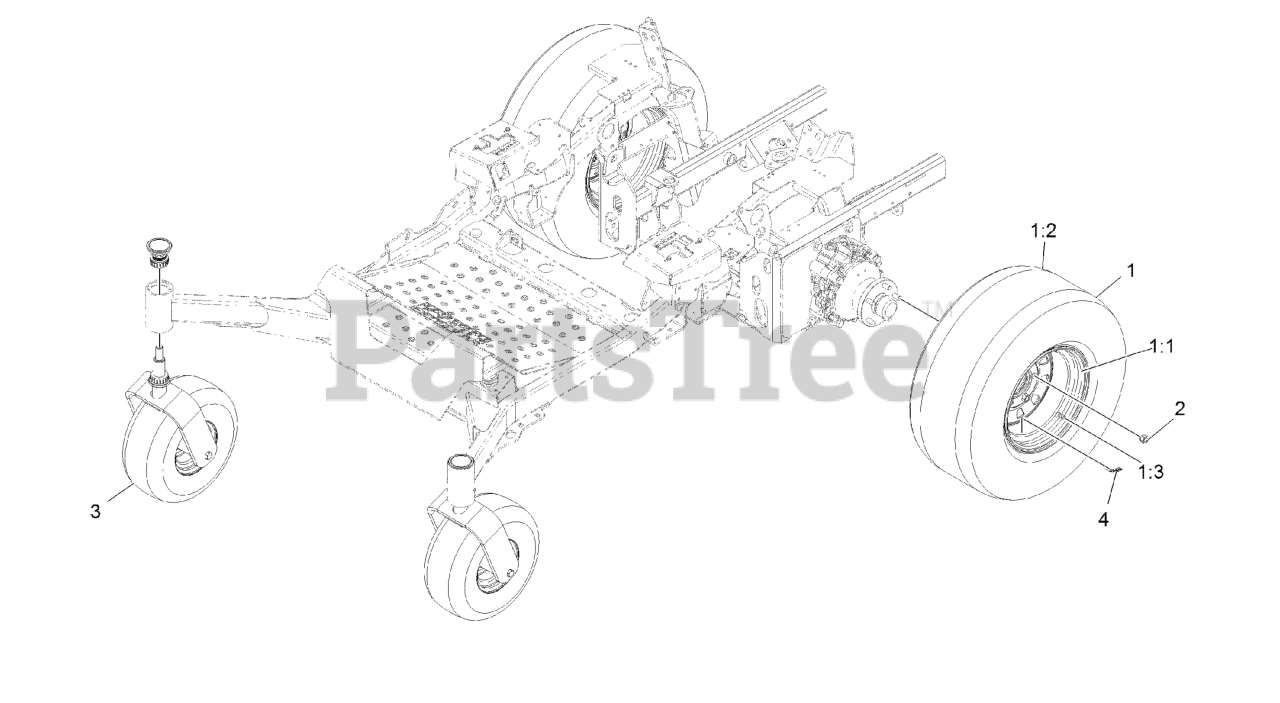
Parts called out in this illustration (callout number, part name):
1	ASM-TIRE 26 X 12-12
1:1	RIM ASM
1:3	Stem-Valve
2	NUT-LUG
3	ASM, Wheel Caster
4	DECAL-TORQUE, WHEEL NUT
